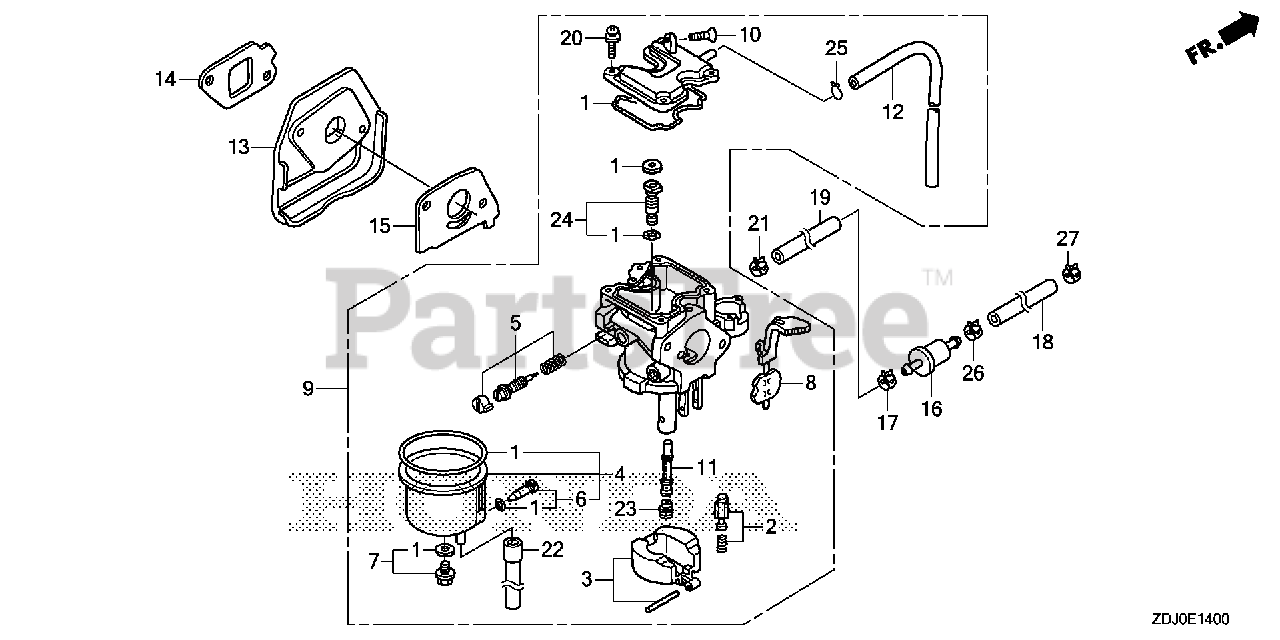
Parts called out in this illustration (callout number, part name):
1	GASKET SET (CARBURETOR NO.)
2	VALVE SET, FLOAT (CARBURETOR NO.)
4	CHAMBER SET, FLOAT (CARBURETOR NO.)
6	SCREW SET, DRAIN (ADVENTURE GREEN) (CARBURETOR NO.)
7	SCREW SET (CARBURETOR NO.)
8	LEVER SET, CHOKE
9	CARBURETOR ASSY. (BF33W A)
10	SCREW, THROTTLE STOP
11	NOZZLE, MAIN
12	TUBE, AIR VENT
13	INSULATOR, CARBURETOR
14	GASKET, INSULATOR
15	GASKET, CARBURETOR
16	FILTER, FUEL
17	CLIP, TUBE (D8.5)
18	HOSE, FUEL (4.2X130) (FKM)
18	HOSE, FUEL (4.2X80) (FKM)
18	HOSE, FUEL (4.2X80)
19	HOSE, FUEL (4.2X160) (FKM)
19	HOSE, FUEL (4.2X210) (FKM)
20	SCREW-WASHER (4X12)
21	CLIP, TUBE (D8.5)
22	BULK HOSE, VINYL (3.5X6.5X8000) (9500(95003-05001-60M) (CARBURETOR NO.)
23	JET, MAIN (#55) Use from Engine SN BF22B D.
23	JET, MAIN (#58) Use from Engine SN BF22B D.
23	JET, MAIN (#60)
24	JET SET, PILOT (#35)
25	CLIP, TUBE (B1 8)
26	CLIP, TUBE (D8.5)
27	CLIP, TUBE (D8.5)
